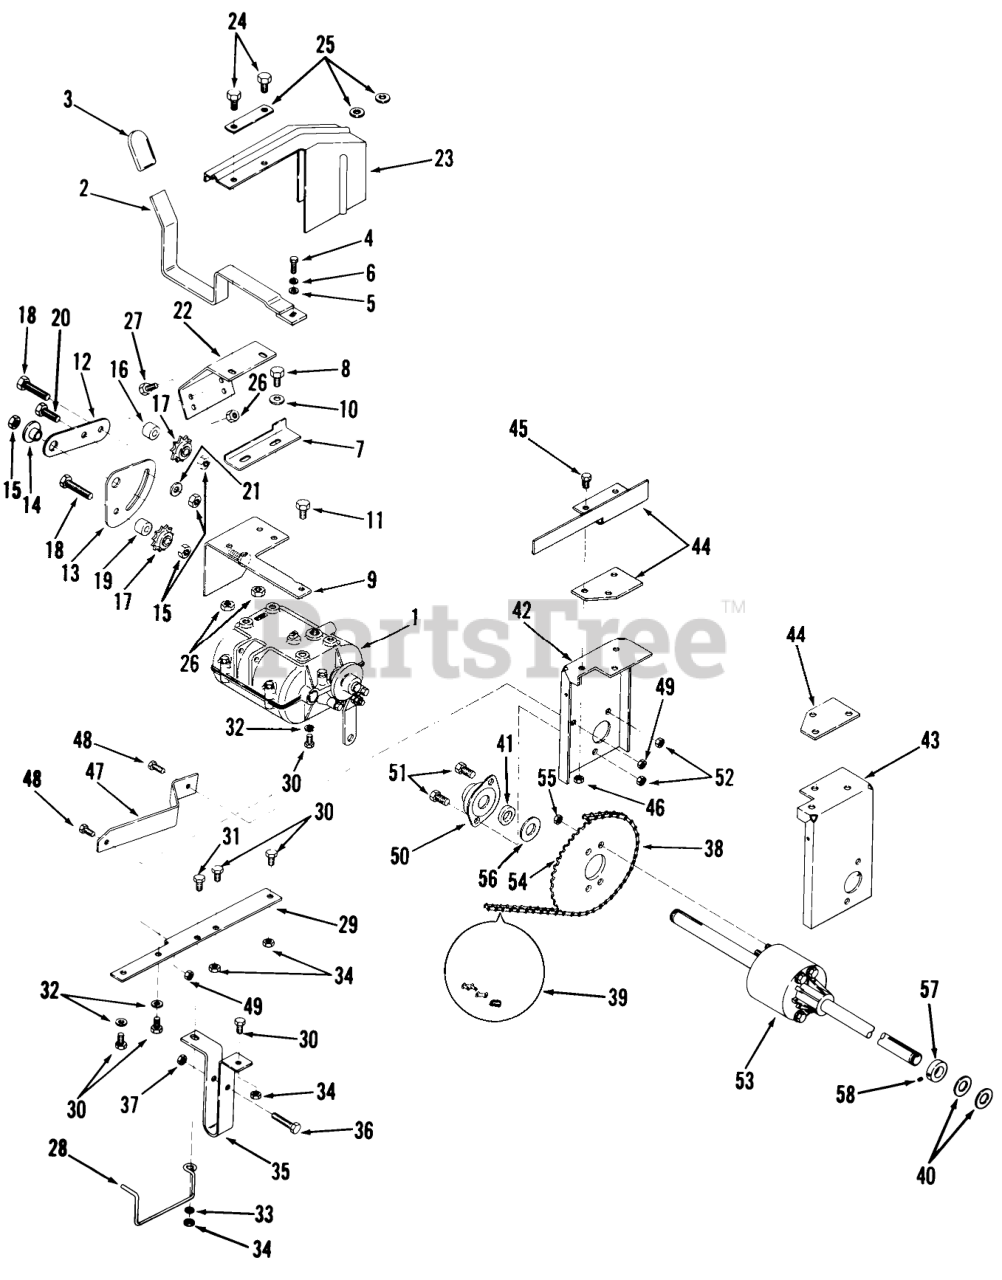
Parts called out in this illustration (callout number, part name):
1	Transmission-Peerless Mod 724A
2	Shift Lever
4	Bolt 1/4-28 X 7/8
5	WASHER
6	Washer
7	Stop-Reverse
8	Bolt
9	ASSY-IDLER SUPPORT
10	WASHER 5/16 SAE
11	Screw
12	Plate-Upper Idler
13	Plate-Lower Idler
14	SPACER-BUSHING
15	Nut
16	SPACER-SPROCKET
17	IDLER-SPROCKET
18	Bolt
19	SPACER
20	BOLT
21	Washer
22	Trans. Stiffener
23	GUARD-CHAIN
24	Bolt
25	Plate-Chain Guard
25	WASHER 5/16 SAE
26	Nut
27	Bolt
28	Snap Ring
28	Belt Guide
29	Washer-Thrust
